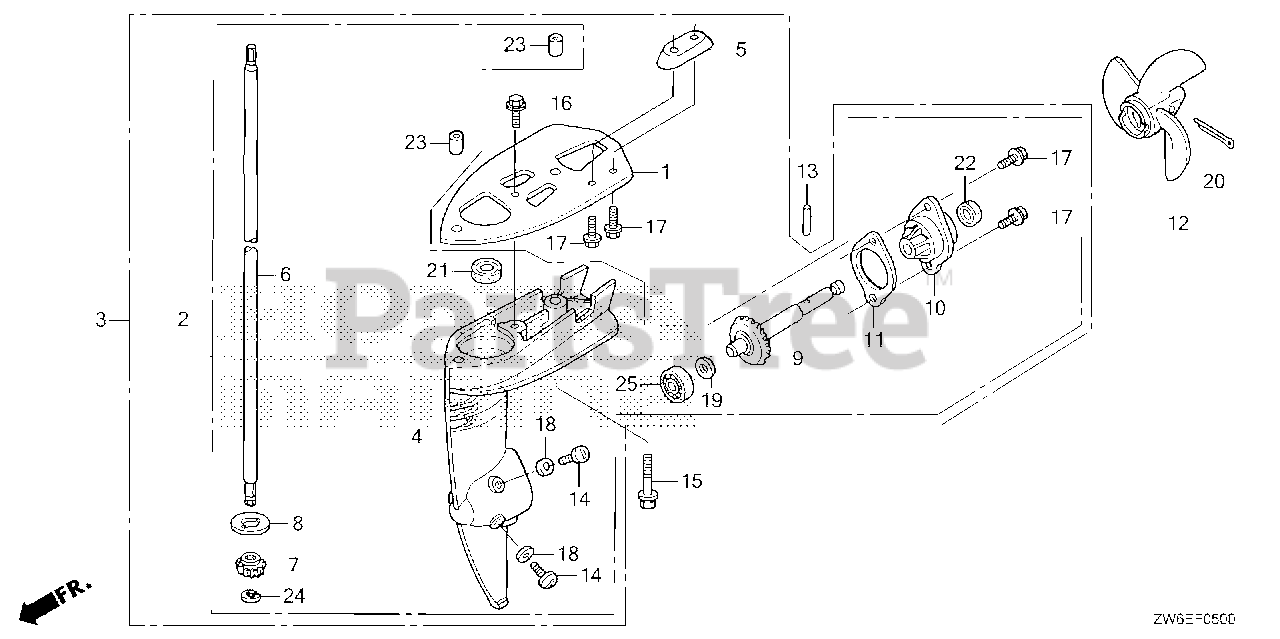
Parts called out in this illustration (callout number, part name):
2	CASE ASSY., GEAR *NH246* (S) (LOOSY GRAY)
4	CASE, GEAR *NH246* (LOOSY GRAY)
6	SHAFT, VERTICAL (S)
7	GEAR, PINION
8	WASHER, PINION THRUST
9	SHAFT, PROPELLER
10	HOLDER ASSY., PROPELLER SHAFT *NH246* (LOOSY GRAY)
11	GASKET, PROPELLER SHAFT HOLDER
12	PROPELLER, THREE-BLADE *NH283* (STIN GRAY)
13	PIN, SHEAR
14	BOLT, OIL CHECK
14	BOLT, OIL CHECK (8X8)
15	BOLT-WASHER (6X35)
17	BOLT, FLANGE (6X16) (SUS)
18	WASHER, NYLON (8MM)
19	WASHER, GEAR (1.00) (A)
20	PIN, SPLIT (3MM)
20	PIN, SPLIT (3.0)
21	SEAL, WATER (11X21X8)
22	SEAL, WATER (11X21X8)
23	PIN, DOWEL (8X14)
24	E-RING (6MM)
25	BEARING, RADIAL BALL (6000)
